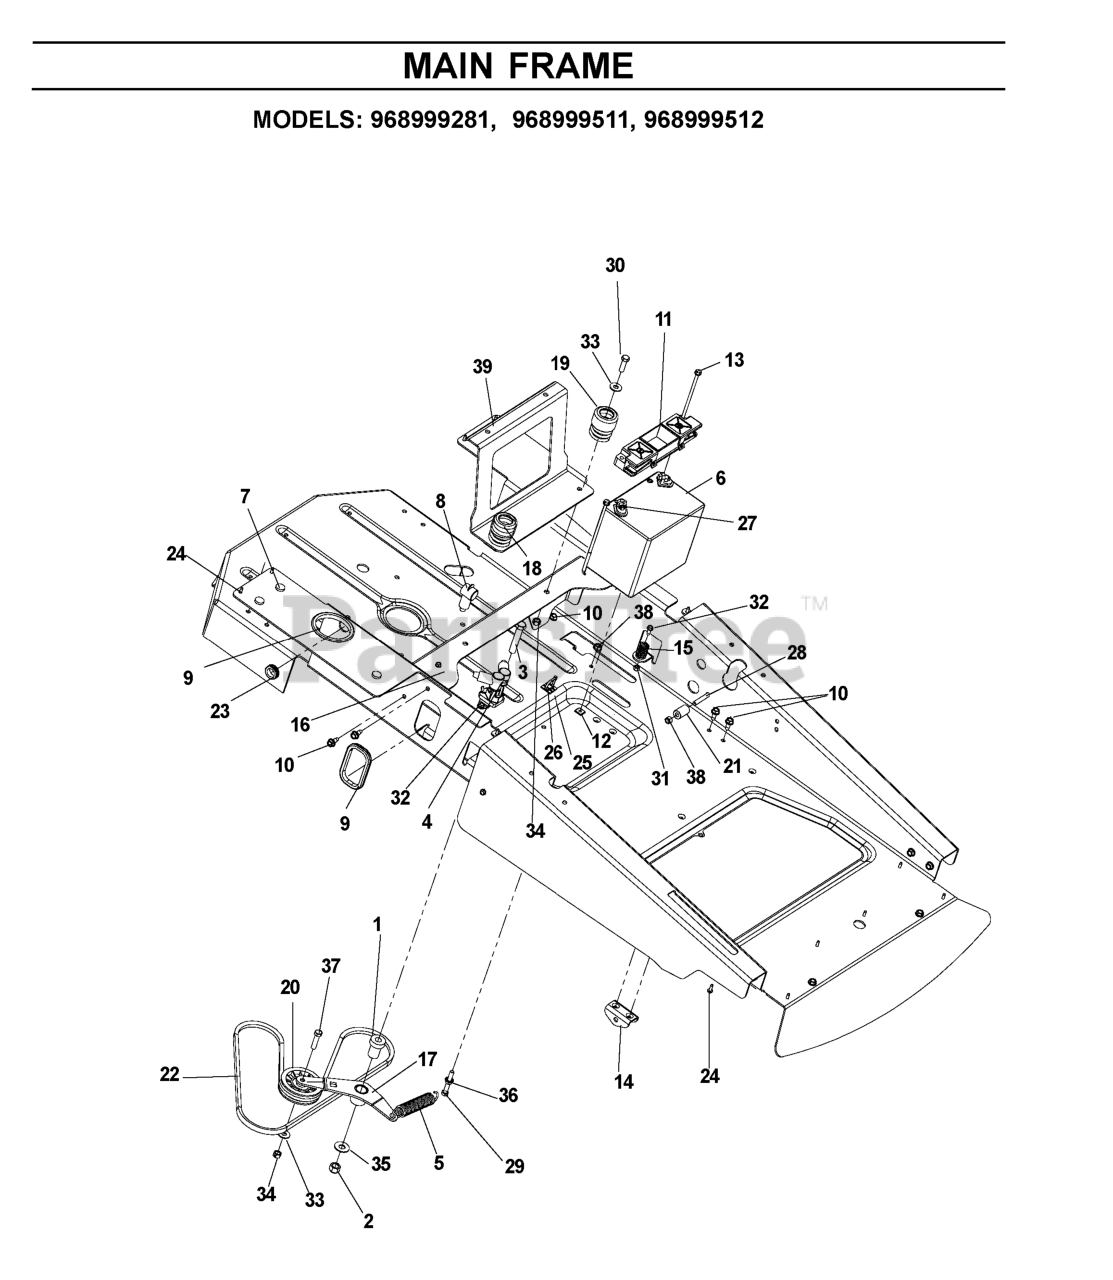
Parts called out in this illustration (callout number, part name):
1	IDLER SPINDLE
2	NUT 1/2-13 HEX NYLOC ZD
3	HCS 1/2C X 2 3/4
6	BATTERY, 12 V 330 AMP
7	GROMMET, BUMPER
10	BOLT 5/16-18 X 3/4
11	BATTERY HOLD DOWN
12	PUSH NUT-NYLON
13	BOLT - 1/4-20 X 7.5
14	BRACKET, DECK HANGER
15	SPRING, RETURN TO NEUTRAL
16	REAR SEAT SUPPORT ORANGE
17	PUMP IDLER WELDMENT
18	SPRING, SEAT
19	CAP, SPRING COVER
20	PULLEY, IDLER RAKE & ZTR
21	MOTION LIMITER
22	BELT, HYDRO PUMP
23	GROMMET, FUEL LINE
24	SCR #10-12X1-1/2HEX WASH HD ZD
25	MOUNTING BLOCK CABLE TIE
26	TIE, PLASTIC
27	HCS 5/16C X 3/4
28	HCS 5/16-18X2
30	HCS 3/8C X 1 1/4 GR5
31	NUT.1/4-20.HEX.NYLOC.ZD
32	SCREW 1/4 X 5/8
33	WASHER 3/8 FLAT
34	NUT 3/8C CENTERBLOCK
35	WASHER 1/2 FLAT
36	NUT 5/16C WHIZ
37	HCS 3/8C X 1 1/2
38	NUT 5/16 NYLOC
39	BRACKET, FRT SUPPORT, BLACK
